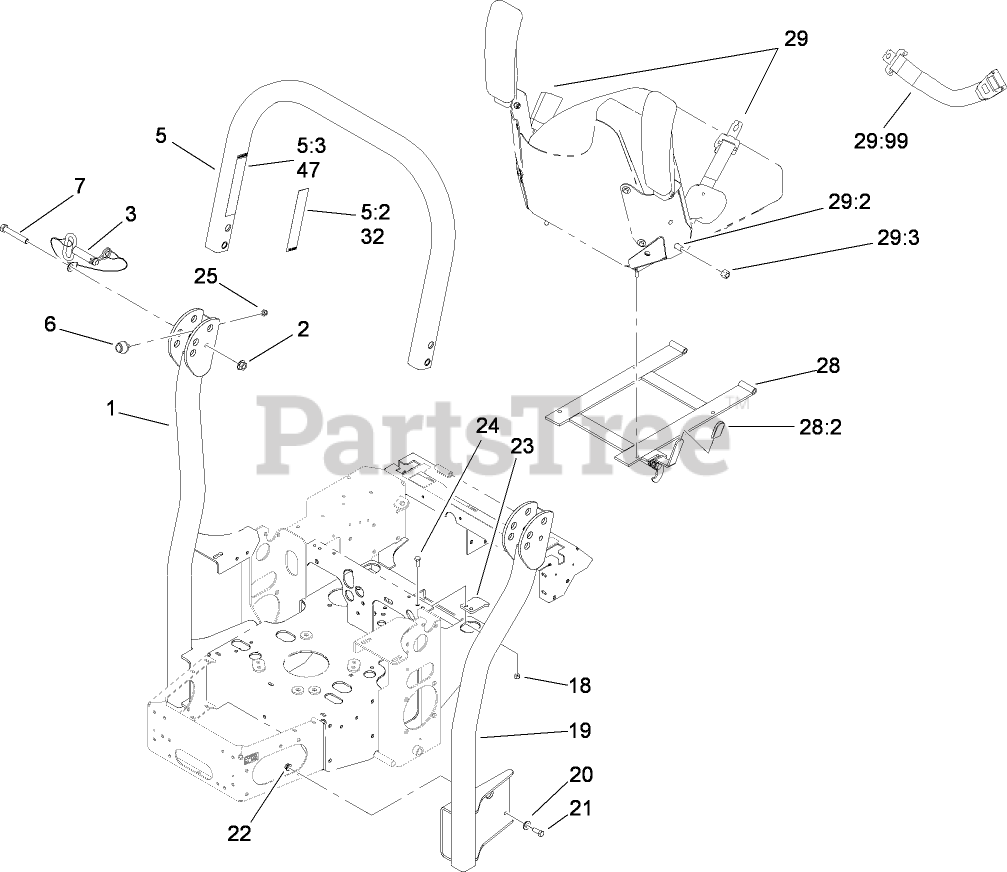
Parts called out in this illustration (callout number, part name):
1	LH TUBE SUPPORT ASM
2	NUT-HF
3	PIN-FOLD, ROPS
5	Upper Tube ASM
5:3	DECAL-WARNING, FOLDING ROPS
6	BUMPER-RUBBER
7	SCREW-HH
18	NUT-LOCK, NI
19	RH TUBE SUPPORT ASM
20	WASHER-BELLEVILLE
21	SCREW-HH
22	NUT-HHF, WHIZ
23	CATCH-LATCH, SEAT
24	SCREW-HH
25	NUT-LOCK, NI
28	SEAT FRAME AND LATCH ASM
28:2	GRIP-LEVER
29	RETRACTABLE SEATBELT KIT
29:2	SCREW-HH
29:3	NUT-LOCK
29:99	SEAT BELT EXTENSION KIT
32	DECAL-WARNING
47	DECAL-WARNING, FOLDING ROPS
